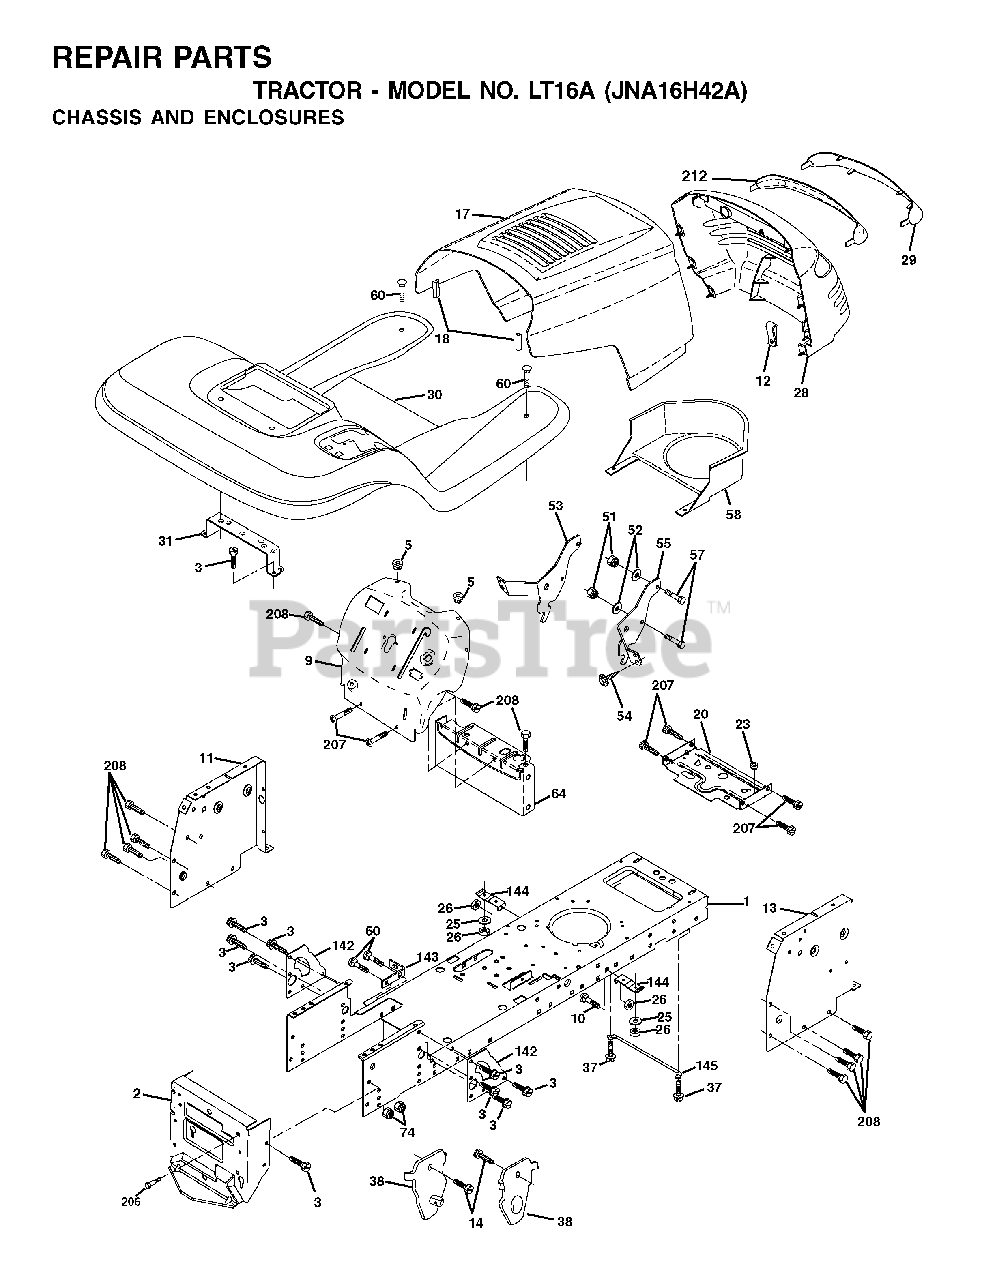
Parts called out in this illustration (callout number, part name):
1	CHASSIS STAMPING
2	DRAWBAR, 12GA
3	SCREW 3/8-16X3/4
5	BUMPER.RUBBER.HOOD
10	BOLT D
11	PANEL DASH LH
13	DASH PANEL RH
18	BUMPER HOOD T
20	PLATE MTG
23	GROMMET T
25	WASHER
26	NUT
38	BRACKET.ASM.PIVOT.MOWER.REAR
51	LOCKNUT
53	BRACKET.GRILLE.LH
57	BOLT
58	AIR DUCT P/L/LT
64	DASH LOWER
74	LOCKNUT
142	PLATE
143	BRACKET, SWAY BAR
144	BRKT, FOOT REST
145	ROD PIVOT CHASSIS/HOOD
206	SHOULDER BOLT 5/16-18TT
207	SCREW, 5/16-18 X 1/2
208	SCREW 3/8-16X1/2
